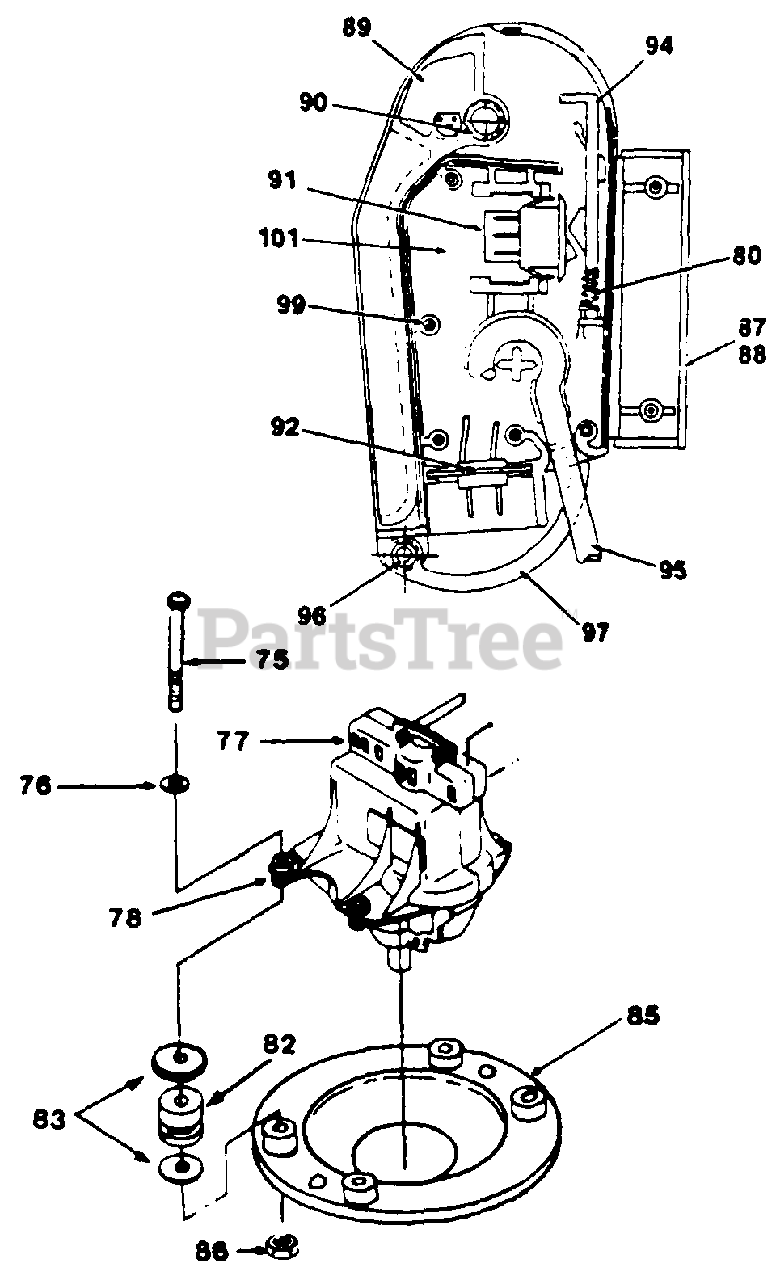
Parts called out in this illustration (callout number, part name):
75	Screw
76	Washer
77	Motor & Switch Ass'y. Complete
78	Insulator
80	Latch Spring
82	Grommet Assembly
83	Washer
85	Motor Shield
86	Lock Nut 1/4"-20
87	Housing - Upper Half
88	Housing - Lower Half
89	Handle - Switch
90	Spring
91	Switch
92	Plug Assembly
94	Latch
95	Cord Assembly
96	Spring - Plug Retainer
97	Plug Retainer
